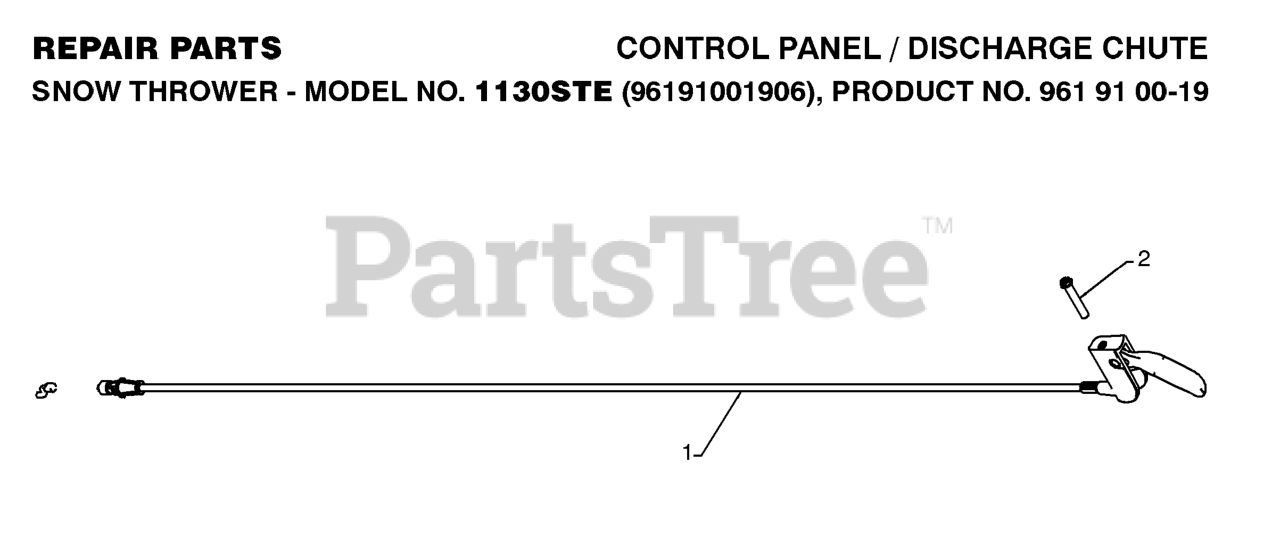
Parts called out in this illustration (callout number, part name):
1	Battery 12 Volt 25 Amp
1	STEERING.CONTROL.SNOW.BLUE
2	BOLT.HEX.1/4.X.3/4.DICHROMATE
8	BOX.BATTERY.MOUNT.FRONT.LT
16	SWITCH INTERLOOK PUSH-IN
21	HARNESS ASSY LIGHT
24	CABLE.BATT.POS.WIRE.TG.DA SOL
25	CABLE.STARTER.6G.BL/RED.17.5
26	FUSE 20AMP
27	NUT
28	CABLE GROUND 6 GA 21" 90T BLK
29	SWITCH.SEAT.DELTA.OPC.
30	SWITCH.IGN.DELTA.W.LGH.ROS
33	KEY.CHAIN.BLISTER.PACK.GEN.INT
40	HARNESS.IGN.DASH.HUQ/P
41	SCREW
42	TERMINAL COVER
43	SOLENOID.W/BRASS.PLUNGER
46	RP.GUAGE.SRVCMNDR.HRMTR.
50	RP.PTO.SWITCH.8 TERMINAL.BLACK
55	SCREW 5/16"
59	OUTLET.12-VOLT
71	HARNESS-CHASSIS SUB
79	BULB HOLDER ASM.
90	COVER.TERMINAL.BATTERY
91	STRAP.BATTERY.MOUNT.FRONT(2 2)
92	HARNESS.PIGTAIL.CONSLE
93	SCREW.PLASTITE
94	MODULE.REVERSE.ROS
99	SCREW HEXWSHR 1/4-20X3/4
101	PIGTAIL.MATNLK.NEW.HAR
103	HARNESS PIGTAIL 12V OUTLET
